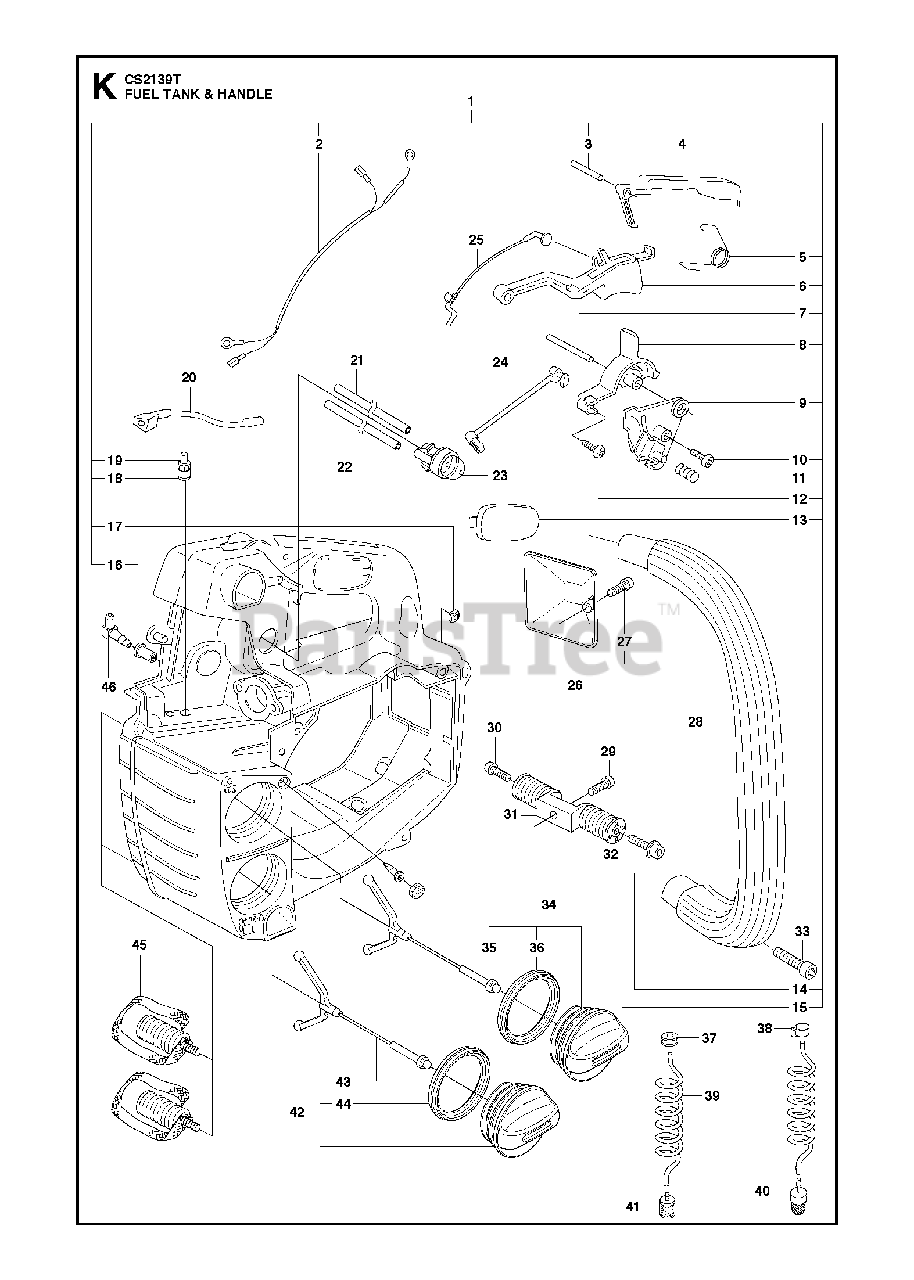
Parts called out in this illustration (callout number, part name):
1	TANK UNIT ASSY
2	CABLE ASSY
3	PIN 3X25
4	THROTTLE LOCK
5	SPRING
6	THROTTLE TRIGGER
7	PIN
8	CHOKE
9	PLATE
10	SCREW
11	SPRING
12	SCREW
13	HANDLE INSERT
14	VALVE-CHECK (DUCKBILL)
15	PLUG
16	SLEEVE
17	NUT
18	FUEL TANK VENT
19	CAP
23	AIR PURGE BUBBLE
24	CHOKE ROD
26	SPARK PLUG COVER ASS
27	SCREW
28	FRONT HANDLE
31	VIBRATION ABSORBER
34	TANK CAP LIGHT GRAY
35	HOLDER
36	SEALING
37	FUEL TANK BUSHING
38	CLAMP
39	FUEL HOSE
40	OIL PLUMMET
41	FUEL FILTER
42	TANK CAP
43	HOLDER
44	SEALING
45	ANTI-VIBE ELEMENT
